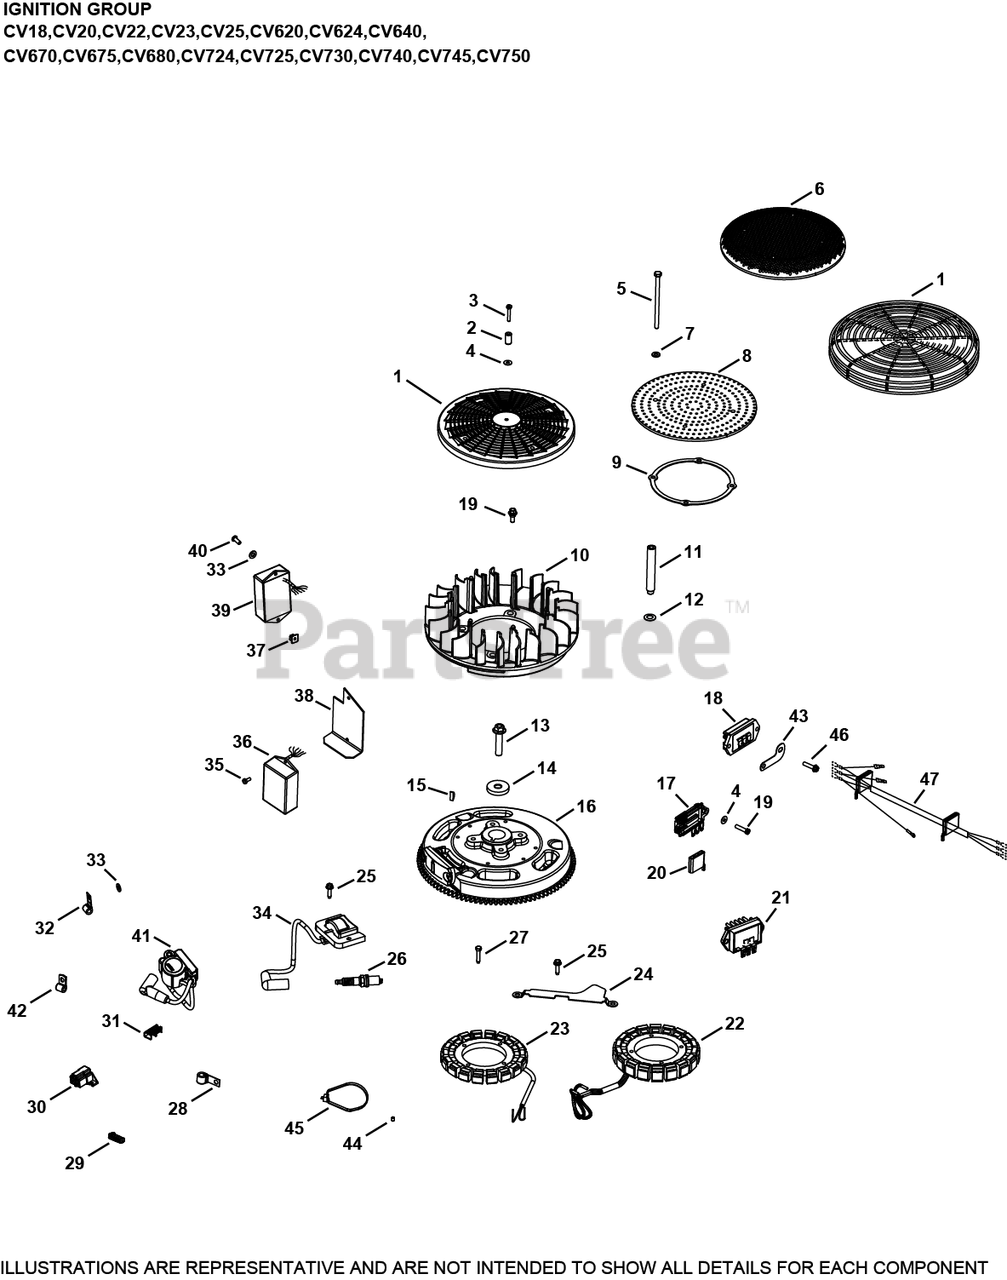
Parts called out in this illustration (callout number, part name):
5	SCREW, CAP M6X1.0X99.5
6	SCREEN, GRASS
7	WASHER, FLAT 1/4" (O.D. 5/8")
9	RING, SUPPORT USE 25 141 08-S
10	FAN USE 24 755 253-S
12	WASHER, SPRING 10 MM
13	SCREW, FLG M10X1.5X45 - (#25086361S)
14	WASHER, FLAT 13/32"
15	KEY, 3/16" X 5/8"
18	REGULATOR/RECTIFIER
20	CONNECTOR
23	KIT, 15 / 20 AMP STATOR
25	SCREW, THREAD FORMING - USE 25 086 473-S
26	PLUG, SPARK (STD)
27	SCREW, THREAD FORMING
28	CLIP, CABLE
33	WASHER, FLAT 1/4" (O.D. 1/2")
34	KIT, MODULE IGNTN (CDI FIXED)
43	BRACKET, GROUND STRAP USE 24 518 12-S
44	SCREW, SKT SET #10-24X1/4"
46	SCREW, HEX FLANGE HI-LO
